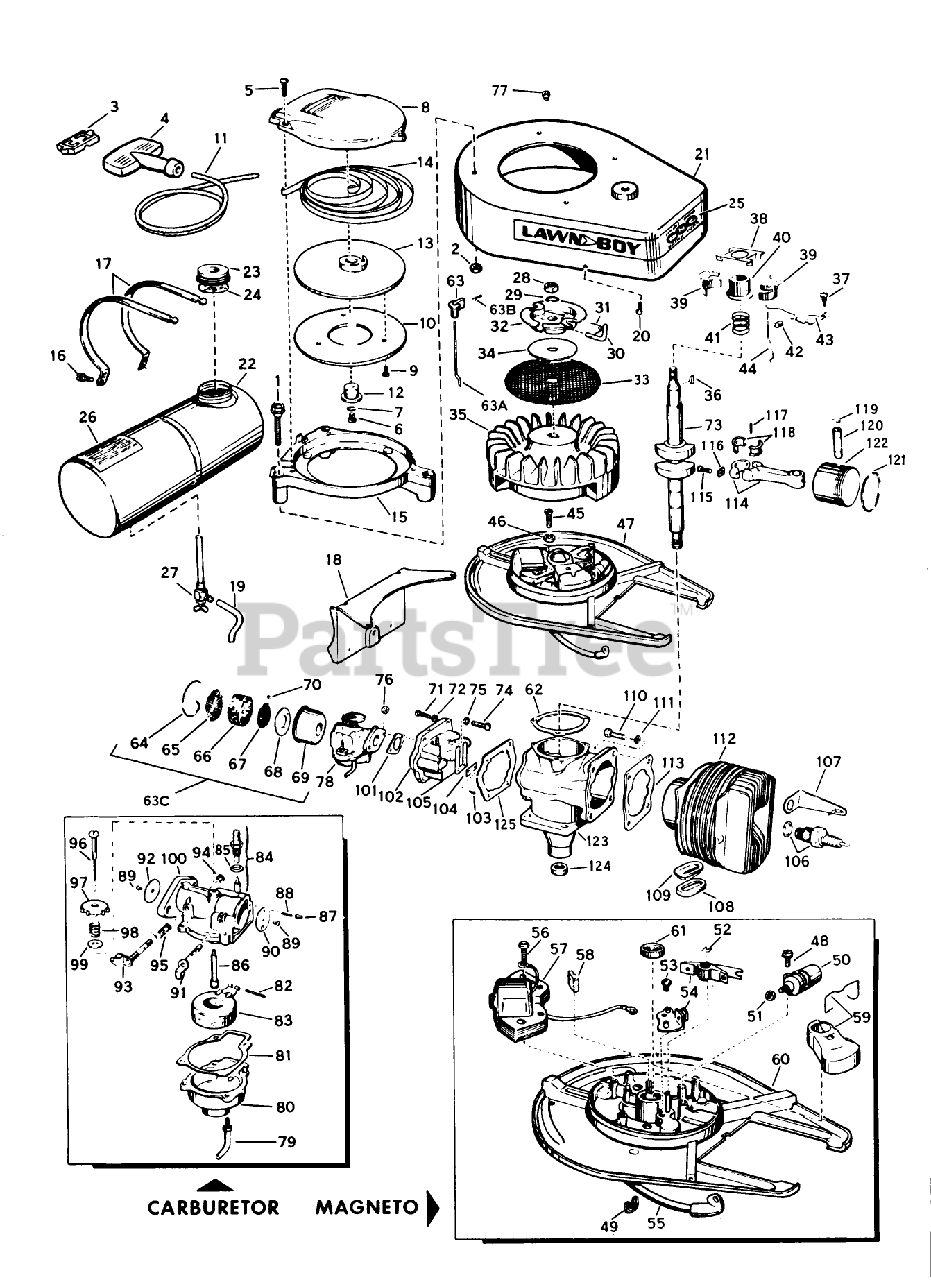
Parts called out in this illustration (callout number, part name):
10	Plate-Pulley
14	RECOIL SPRING
20	SCREW S
23	Gas Cap
25	Decal-"LAWN-BOY"
26	Decal-Instruction
27	VALVE&SCREEN SM
30	PIN - STARTER
40	COLLAR S
42	WEAR BLOCK S
43	GOVERNER LEVER AY
44	GOVERNOR ROD S
54	BREAKER AY. S
62	GASKET S
63B	Cotter Pin
66	ELEMENT
68	BACK-UP PLATE
71	SCREW S
76	STOP NUT
89	Screw-Choke Disc
95	SPRING
96	NEEDLE AY. S
98	Spring-Ndl. Adj.
101	GASKET S
104	PLATE-BACKUP, REED
106	Spark Plug
108	GASKET S
113	GASKET S
118	LINER ASM
